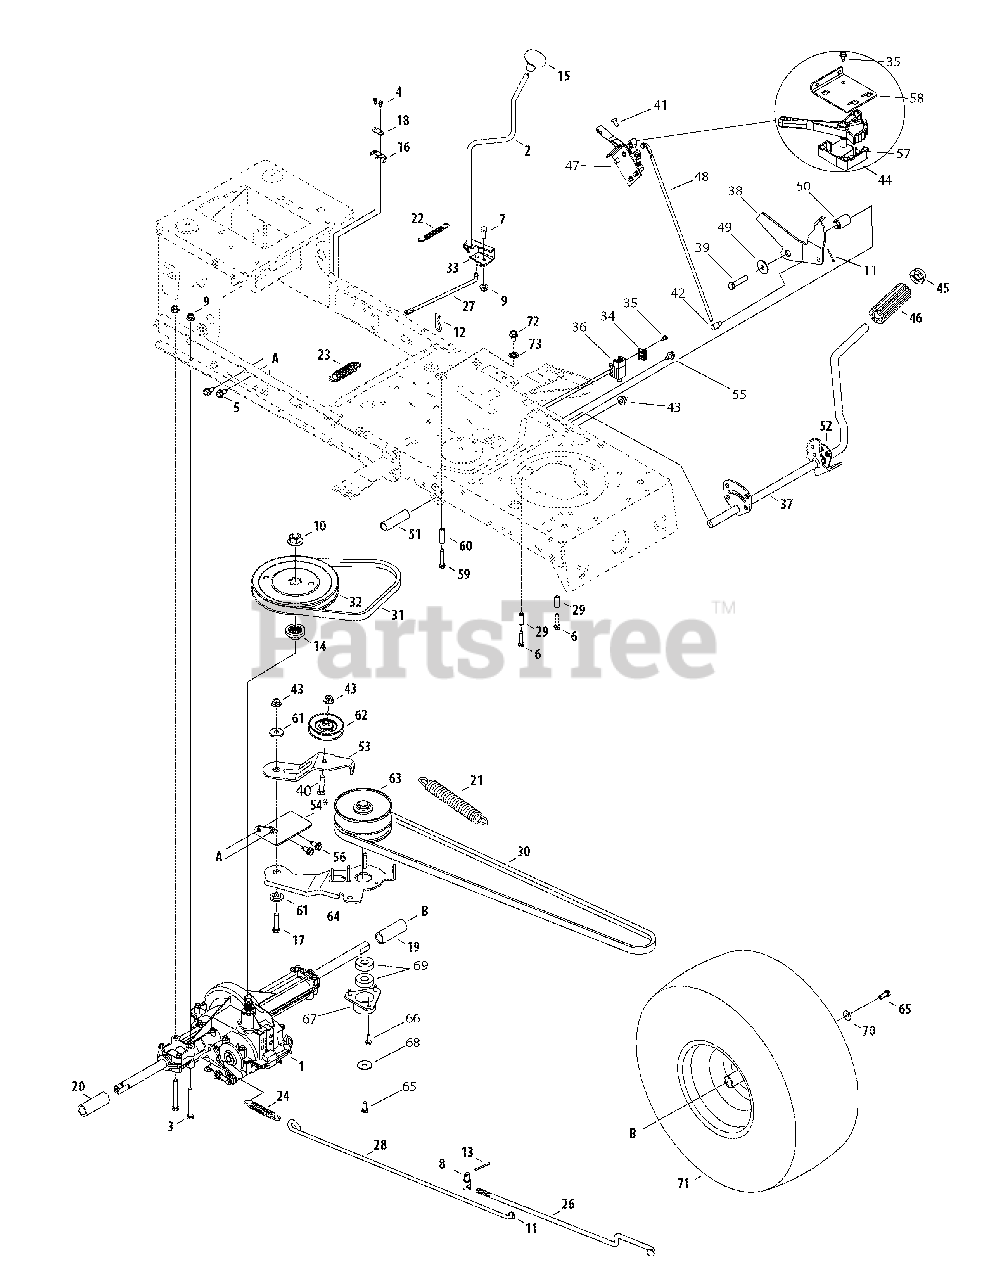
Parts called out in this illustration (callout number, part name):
1	Transmission Ass’y
2	Shift Lever Ass’y
3	Hex Scr 5/16-18 x 2.75
4	Hex Wash HD AB S-Tapp Scr #8-.50
5	S-Tapp Scr 5/16-18 x .75
6	Hex Bolt 1/4-20 x 1.25
7	Hex Bolt 5/16-18 x .75" Lg. Gr. 5
8	Ferrule
9	Flange Locknut 5/16-18 Gr. F, Nylon
11	Cotter Pin 3/32 dia x 1.00 Lg.
12	Cotter Pin
13	Cotter Pin 1/8" Dia x 1.25
14	Pulley Hub 5/8" Spline
16	Short Spring Switch
17	Screw, 3/8-16 x 1.75
18	Insulator Nut Plate
19	Sleeve, .758 x .821 x 3.3125
20	Sleeve, .758 x .821 x 2.4375
21	Spring, Extension, 1.15 OD x 7.90
22	Spring, Extension
23	Spring, Extension, .80 OD x 3.28
24	Ext. Spring .59 OD x 4.00 Lg.
25	Flat Washer .344 ID x .625 OD x .063
26	Control Rod, Variable Speed
29	Spacer .260 x .375 x 1.030 Lg.
30	Belt
31	Belt
32	Pulley, V-Type, 7.25 dia.
33	Shift Bracket, Adjustable
34	Switch Plate
35	Hex AB-Tap Scr #10 X .50" Lg.
36	Interlock Switch
38	Latch Ass’y, Engagement (RMC)
39	Hex Screw 3/8-16 x 1.875 Gr. 5
40	6 Speed Shift Control Ass'y
40	7 Speed Shift Control Ass'y
41	Screw, 1/4-20 x .5
42	Adjustment ferrule
43	Flange Lock-Nut 3/8-16 Gr. F Nylon
44	Control Cover
45	Push Cap 5/8" Dia Rod
46	Foot Pad
47	Shift Lever - 6 Speed
47	Shift Lever - 7 Speed
48	Speed Selecter Control Rod
49	Flat Washer .411 ID x 1.25 OD x .10
50	Flange Spacer .390 x .671 x 1.095
51	Spacer .630 ID
53	Idler Bracket
54	Transmission Torque Bracket
55	Self-tapping Screw 5/16-18 x .625
56	Hex Wash. Hd. Scr. 5/16-18 x .75 Lg.
57	Shift Lever Spring
58	Control Bracket
59	Screw, 1/4-20 x 1.625
60	Spacer, .260 x .372 x 1.420
61	Shoulder Spacer
63	Variable Speed Pulley Ass’y 4.75 OD
64	Variable Speed Bracket Ass’y
65	Hex L-Screw 5/16-24 x 0.75 Gr. 5
66	Hex Scrw 1/4-20 x 1.5
68	Flat Washer .22 ID x 1.25
69	Ball Bearing 17 x 40 x 12
70	Cupped Washer .345 ID x .88 OD x .060
72	Hex Wash S-Tapp Scr 1/4-20 x .50
73	Lockwasher 1/4"
